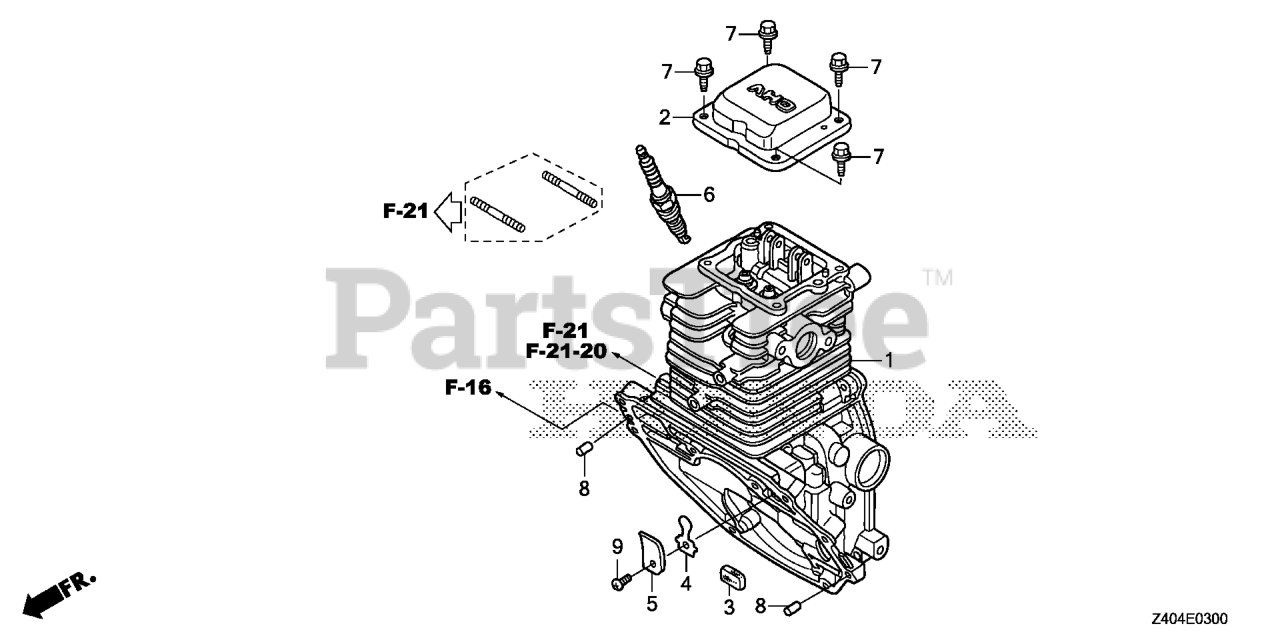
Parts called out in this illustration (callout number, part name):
1	CYLINDER
2	COVER, HEAD
3	FILTER, BREATHER
4	VALVE, OIL OUTLET
5	PLATE, STOPPER
6	SPARK PLUG (LR4C-E) (NGK)
7	BOLT, FLANGE (5X12)
8	ROLLER (6X14.8)
9	SCREW, PAN (3X5)
